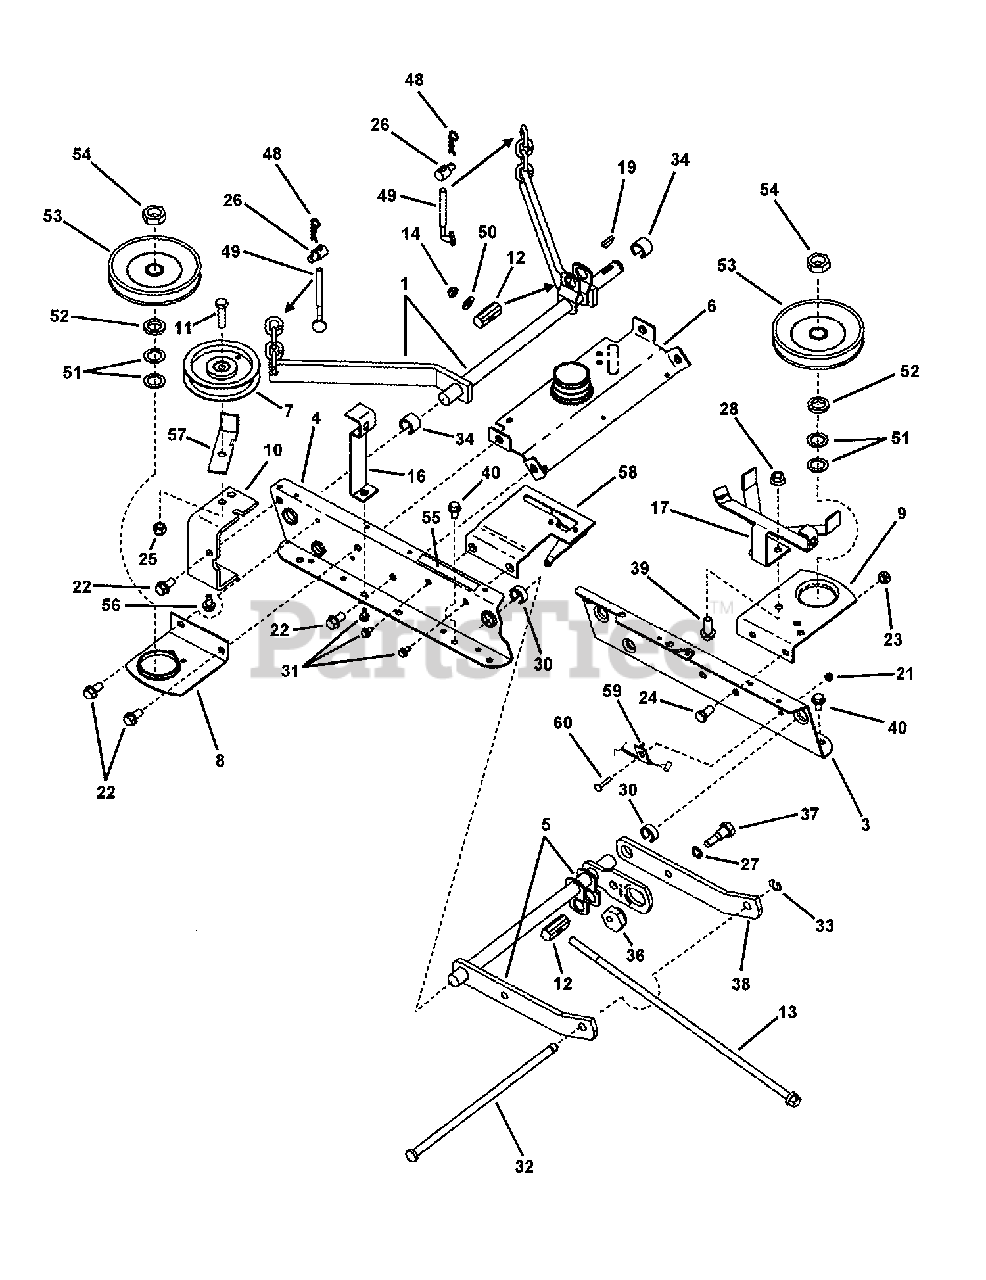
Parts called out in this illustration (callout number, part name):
1	ASSEMBLY, Rear Lift Arm
3	RAIL, Left Half
4	RAIL, Deck Lift, Right Hand
5	STUCTURE, Front Lift Arm
6	WELDMENT, Top Brace
7	IDLER, 4-1/8" Flat
8	BRACE, R.H. Spindle
9	BRACE, L.H. Spindle
10	BRACE/IDLER Mounting Bracket
11	SCREW, 3/8-16 x 1-1/2" Hex Head Cap, GR5
12	PIVOT, Leveling
13	ROD, Leveling
14	NUT, 3/8-24 Hex Top Lock
16	BELT GUIDE, 42"
17	GUIDE, Belt, 42" RER (Weldment)
19	KEY, 3/16 x 7/8" Woodruff
21	NUT, #10-24 Hex Nyloc
22	SCREW, 3/8-16 x 3/4" Hex Washer Self-Tap
23	NUT, 3/8-16 Hex Center Lock
24	SCREW, 3/8-16 x 3/4" Hex Head Cap, GR5
25	NUT, 3/8-16 Hex Nyloc
26	SWIVEL, Adjustable
27	WASHER, 3/8" Internal Tooth Lock
28	NUT, 3/8-16 Hex Flange Lock
30	RING, Front Lift Arm (Red)
31	SCREW, 5/16-18 x 1/2" Hex Washer Self-Tap
32	ROD, Deck Support (Front Lift Arm to Front End)
33	RING, .438 External Retaining
34	RING, Rear Lift Arm (Blue)
36	ECCENTRIC, Leveling
37	BOLT, 3/8-24 x 3/4" Shoulder, GR5
38	ARM, Front Lift (Left Side)
39	BOLT, 3/8-16 x 1" Hex Flange Lock, GR5
40	BOLT, 5/16-18 x 5/8" Hex Flange Lock
48	HAIR PIN, 3/32 x 1-1/2"
49	ADJUSTER, Chain (5/16-18 thread)
50	WASHER, 3/8" Flat SAE
51	WASHER, .77 x 1.13 x .06 Flat
53	PULLEY, 5" O. D.
54	NUT, 3/4-16 Hex Jam, GR 8
55	DECAL, Blade Engagement, 42"
56	SCREW, 5/16-18 x 5/8" Hex Washer Self-Tap
57	BELT GUIDE
58	ASSEMBLY, Clutch Plate
59	CABLE, No-Mow-In-Reverse
60	BOLT, #10-24 x 1" Flat Head Square Neck
